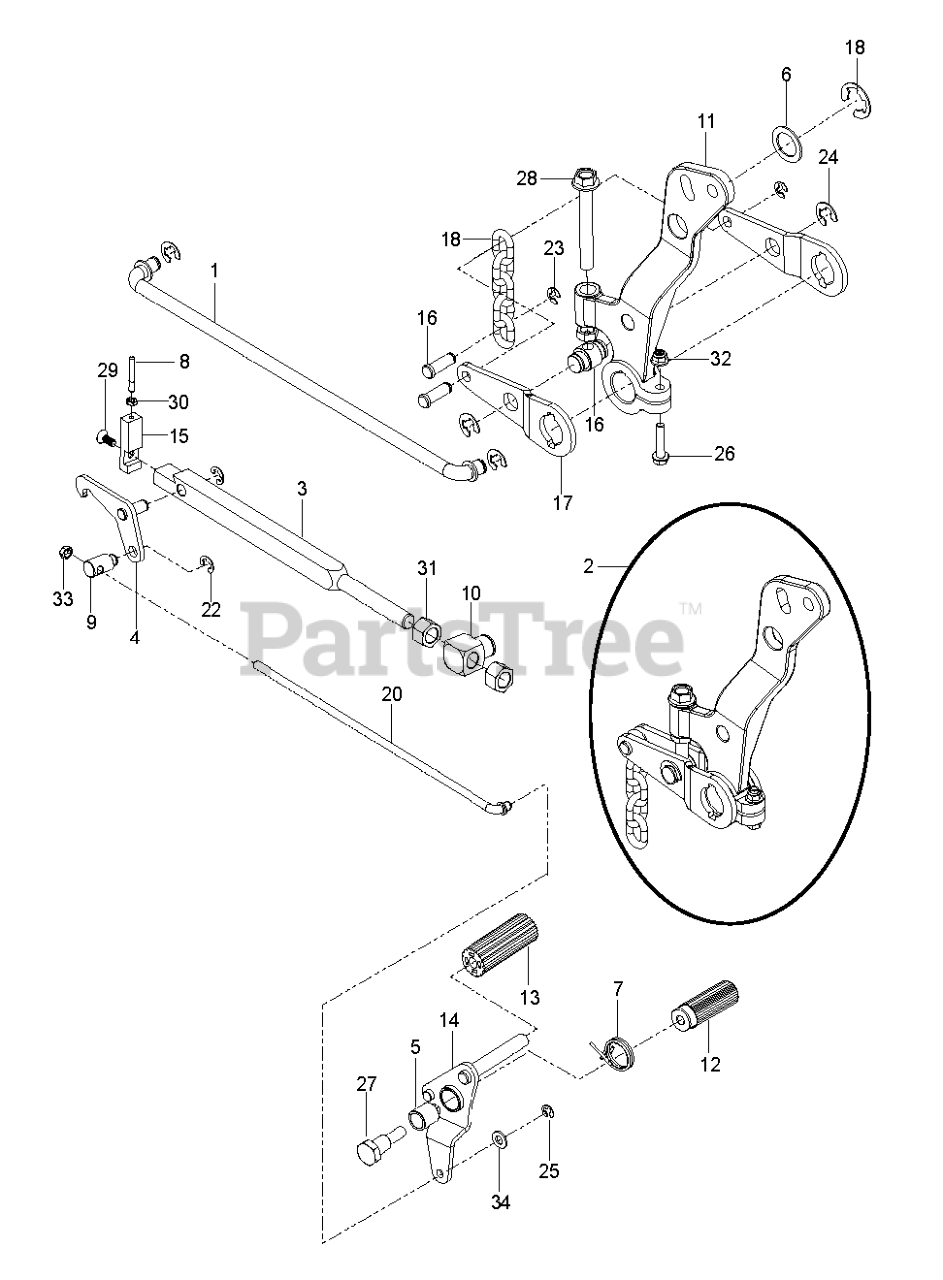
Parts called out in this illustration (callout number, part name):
2	ASSEMBLY, DECK LIFT CRANK
3	BAR, HEIGHT
4	LATCH, HEIGHT WLDMT
5	BUSHING, SLEEVE 3/4 X 1.0
6	MACHINE BUSHING
7	SPRING, TORSION
8	LINK, INDICATOR
9	SWIVEL, HEIGHT LATCH
10	SWIVEL, HEIGHT BAR
11	ARM, LIFT LEVER
12	PAD, FOOT PEDAL
13	PEDAL, DECK HEIGHT
14	PEDAL, RELEASE WLDMT
15	CAP, HEIGHT BAR
16	SHAFT, LIFT TRUNION WSL
17	ARM LIFT BLK
18	LIFT CHAIN
19	PIN, 7/16 CLEVIS
20	ROD, HEIGHT LATCH
21	E-RING 1"
22	E-RING 1/2 (2 2)
23	E-RING 5/8
24	E RING 3/4
25	E RING 3/8"
26	HHFS 5/16-18 X 1.5 GD 5
27	BOLT, SHOULDER
28	HHFS 1/2-13 X 4 GR 5
29	SCREW, 5/16-18 X 3/4 FLAT HEX
30	NUT 1/4-20 JAM
31	NUT 3/4-10 HEX ZD
32	5/16-18 NYLOC FLANGE NUT
33	NUT 3/8-24 JAM
34	WASHER
